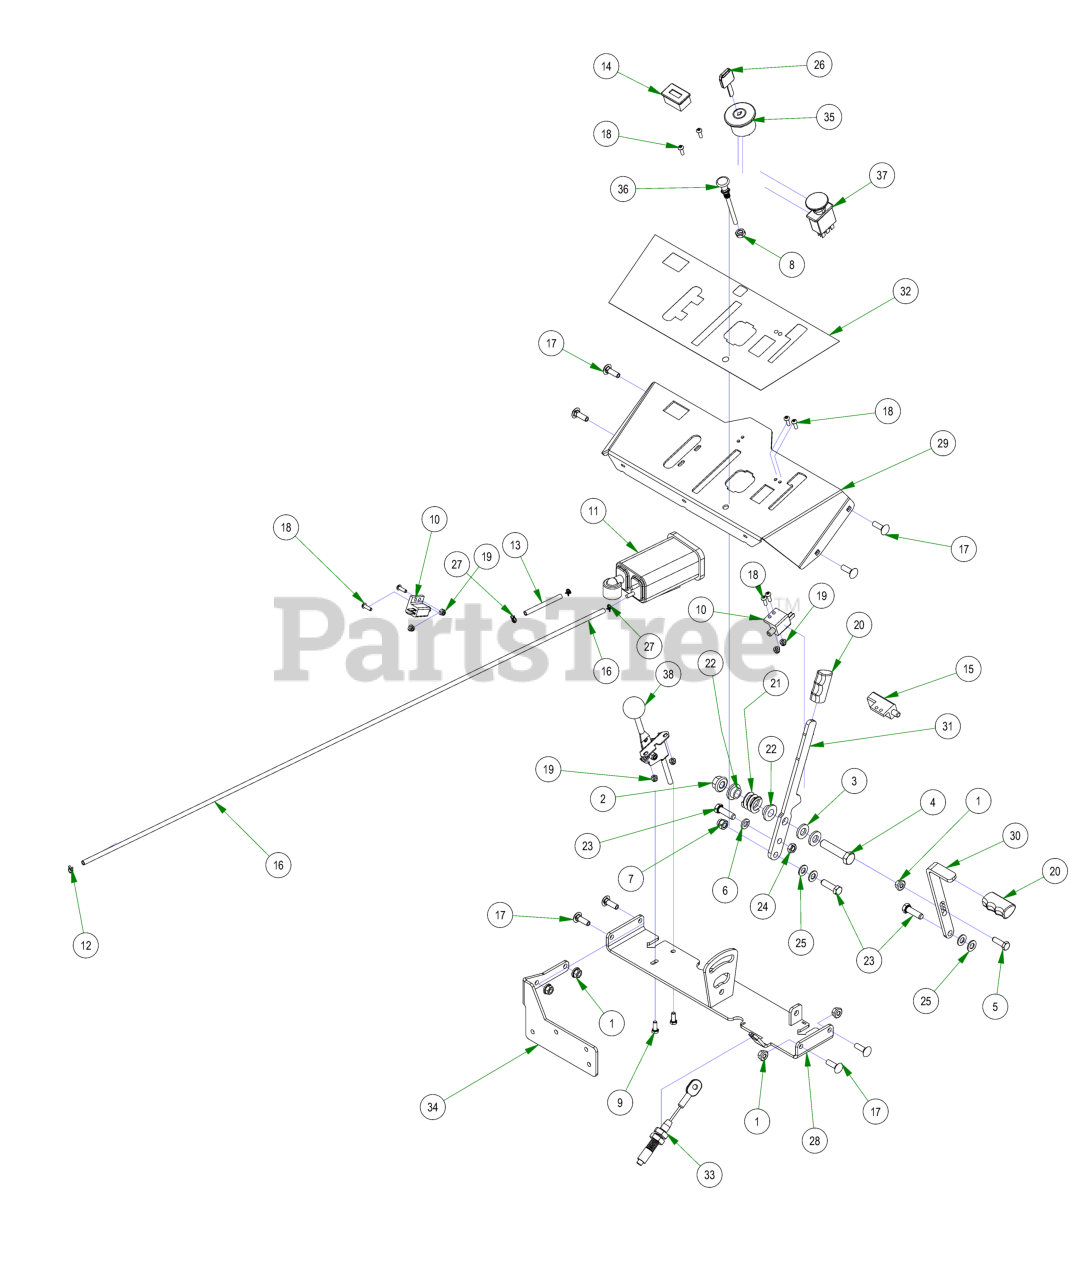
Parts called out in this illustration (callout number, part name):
1	5/16-18 NYLON INSERT FLANGE LOCKNUT ZINC
2	1/2-13 NYLON INSERT FLANGE LOCKNUT ZINC
3	.505 ID X 1.000 OD X .125 THICK FLAT WASHER NYLON
4	1/2-13 X 2-1/4 HEX CAP SCREW (GR.5) ZINC
5	5/16-18 X 1 HEX CAP SCREW (GR.5) ZINC
6	3/8 SPLIT LOCKWASHER ZINC
7	3/8-16 NYLON INSERT LOCKNUT ZINC
8	3/8-24 HEX NUT ZINC YELLOW
9	M6-1.0 X 16MM DIN 933 HEX TAP BOLT (CL 8.8) ZINC
10	safety Switch
11	Carbon Canister for Magnum/MZ
12	3/16" Vinyl Hose Clamp
13	3/16" Clear Vinyl Tubing
14	Tachometer
15	Brake switch 4 prong
16	3/16 Vinyl Tubing, 44"
17	5/16-18 X 1 CARRIAGE BOLT (GR.8) ZINC
18	10-24 X 5/8 BUTTON SOCKET CAP SCREW 18-8 STAINLESS STEEL
19	10-24 NYLON INSERT LOCKNUT ZINC
20	Rubber Brake Grip-cZT/ZT 2013
21	Drive Lever Spring
22	.525 ID SHOULDER WASHER NYLON
23	3/8-16 X 1-1/4 HEX CAP SCREW (GR.5) ZINC
24	3/8-16 HEX JAM 2-WAY REVERSIBLE CENTER LOCKNUT ZINC
25	.390 ID X .750 OD X .062 THK FLAT WASHER NYLON
26	Ignition Key
27	8.6mm Hose Clamp
28	2020 Walk Cross Support Weldment
29	2020 Walk Control Panel
30	Walk Brake Handle
31	Walk Behind Speed Control Lever
32	2020 Walkbehind Control Panel Decal
33	Brake Cable
34	2022 Walk Behind Relay Mount Plate - Painted
35	Ignition Switch
37	PTO Switch
38	Throttle Lever Assembly
